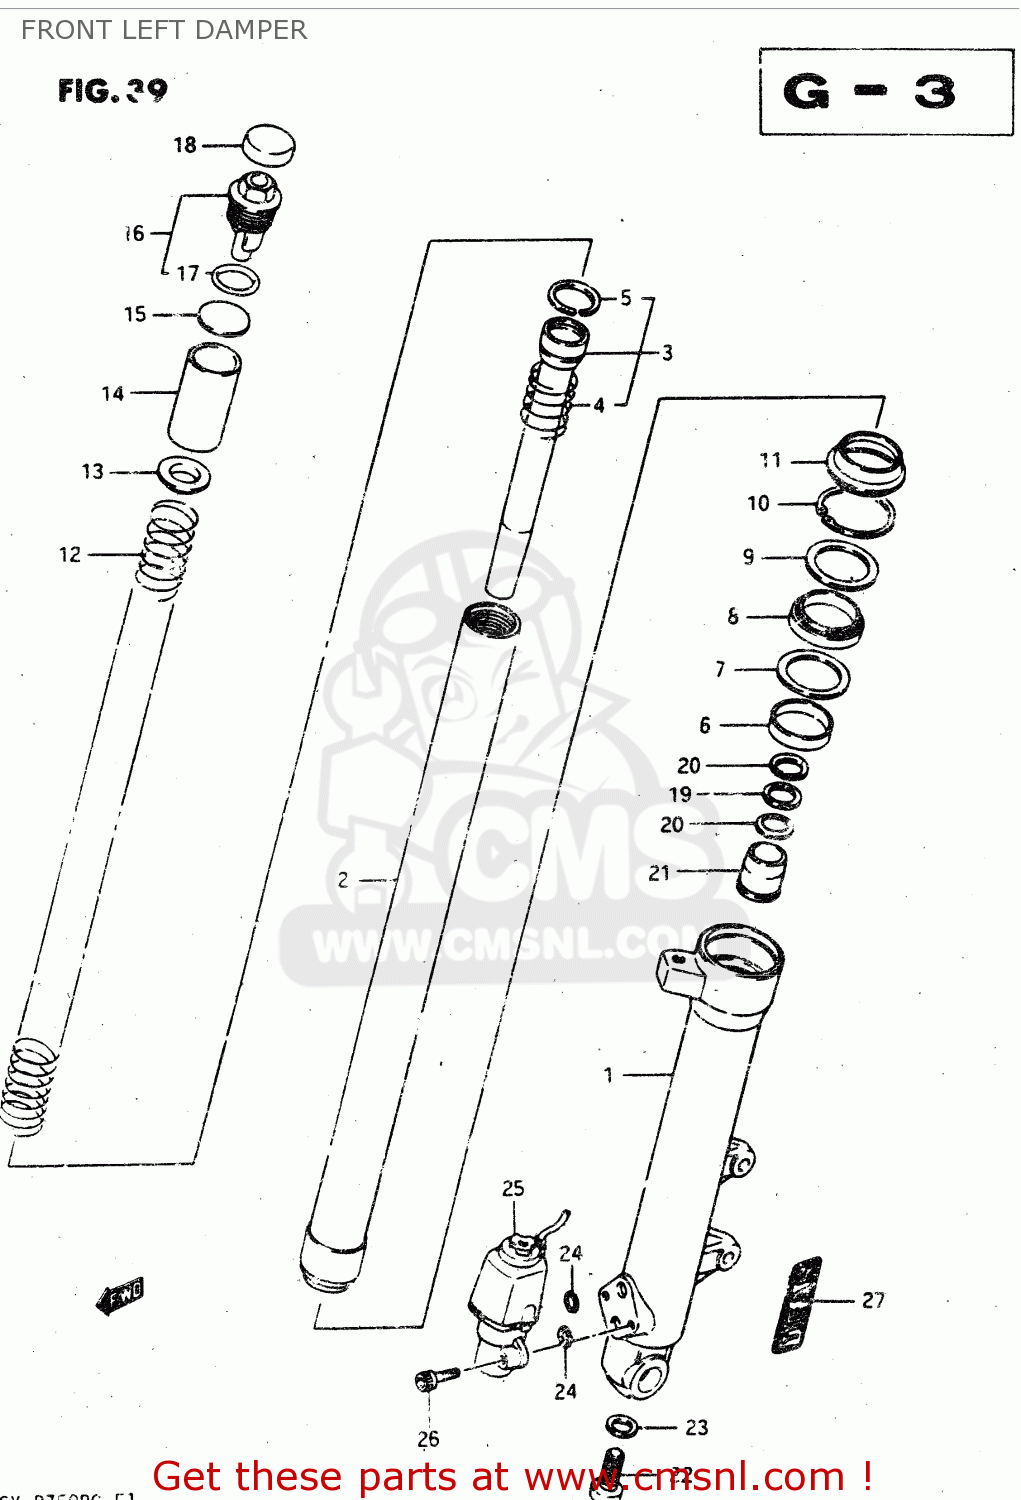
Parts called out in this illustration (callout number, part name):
1	TUBE,OUTER,LEFT
2	TUBE,FORK INNER
3	CYLINDER
4	SPRING,REBOUND
5	RING,FR FORK PISTON
6	METAL,SLIDE
7	WASHER,FORK OIL SEAL
8	OIL SEAL,FRONT FORK
9	WASHER,FORK OIL SEAL
10	RING,OIL SEAL STOPPER
11	DUST SEAL,FRONT FORK
12	SPRING,FRONT FORK
13	WASHER
14	SPACER
15	WASHER,FR FORK SPRING
16	CAP
17	O RING
18	CAP
19	WASHER,OIL LOCK PIECE
20	SPRING,FORK OIL LOCK PIECE
21	PIECE,OIL LOCK
22	BOLT(14X25)
23	GASKET (NAS)
24	O RING
25	P.D.F. ASSEMBLY
26	BOLT
